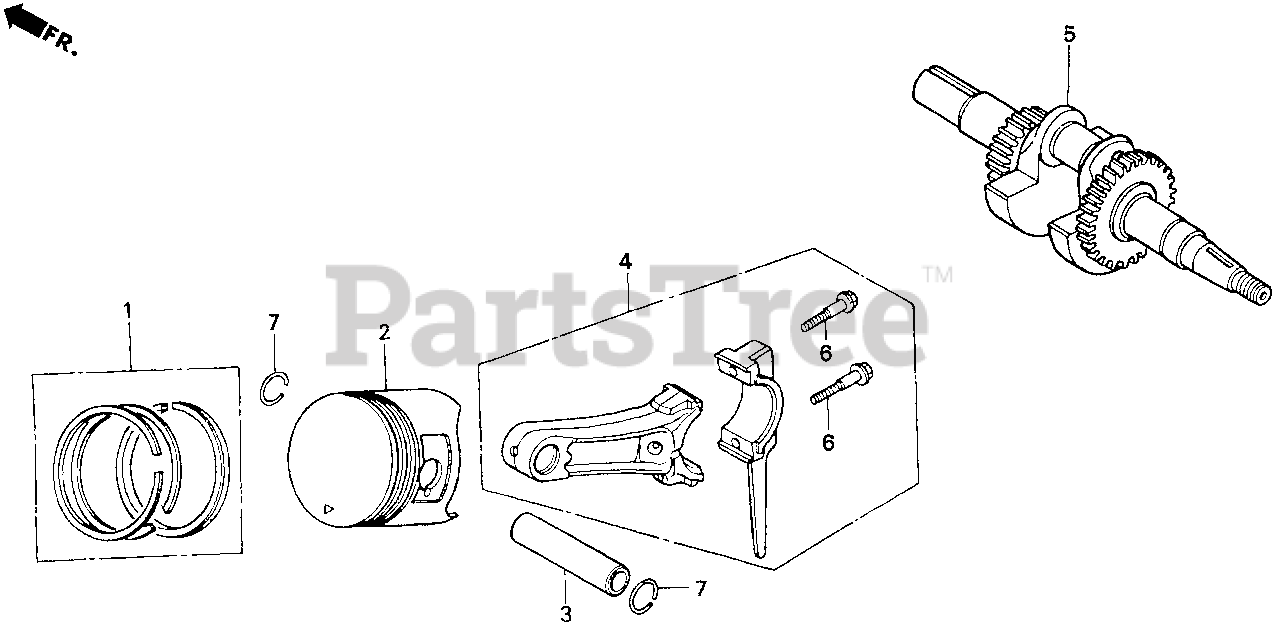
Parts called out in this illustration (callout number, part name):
1	RING SET, PISTON (STD)
1	RING SET, PISTON (OS 0.25)
1	RING SET, PISTON (OS 0.50)
1	RING SET, PISTON (0.75)
2	PISTON (STD)
2	PISTON (OS 0.25)
2	PISTON (OS 0.50)
2	PISTON (0.75)
3	PIN, PISTON
4	ROD ASSY., CONNECTING (US 0.25)
4	ROD ASSY., CONNECTING
5	CRANKSHAFT (S-TYPE)
6	BOLT, CONNECTING ROD
7	CLIP, PISTON PIN (18MM)
